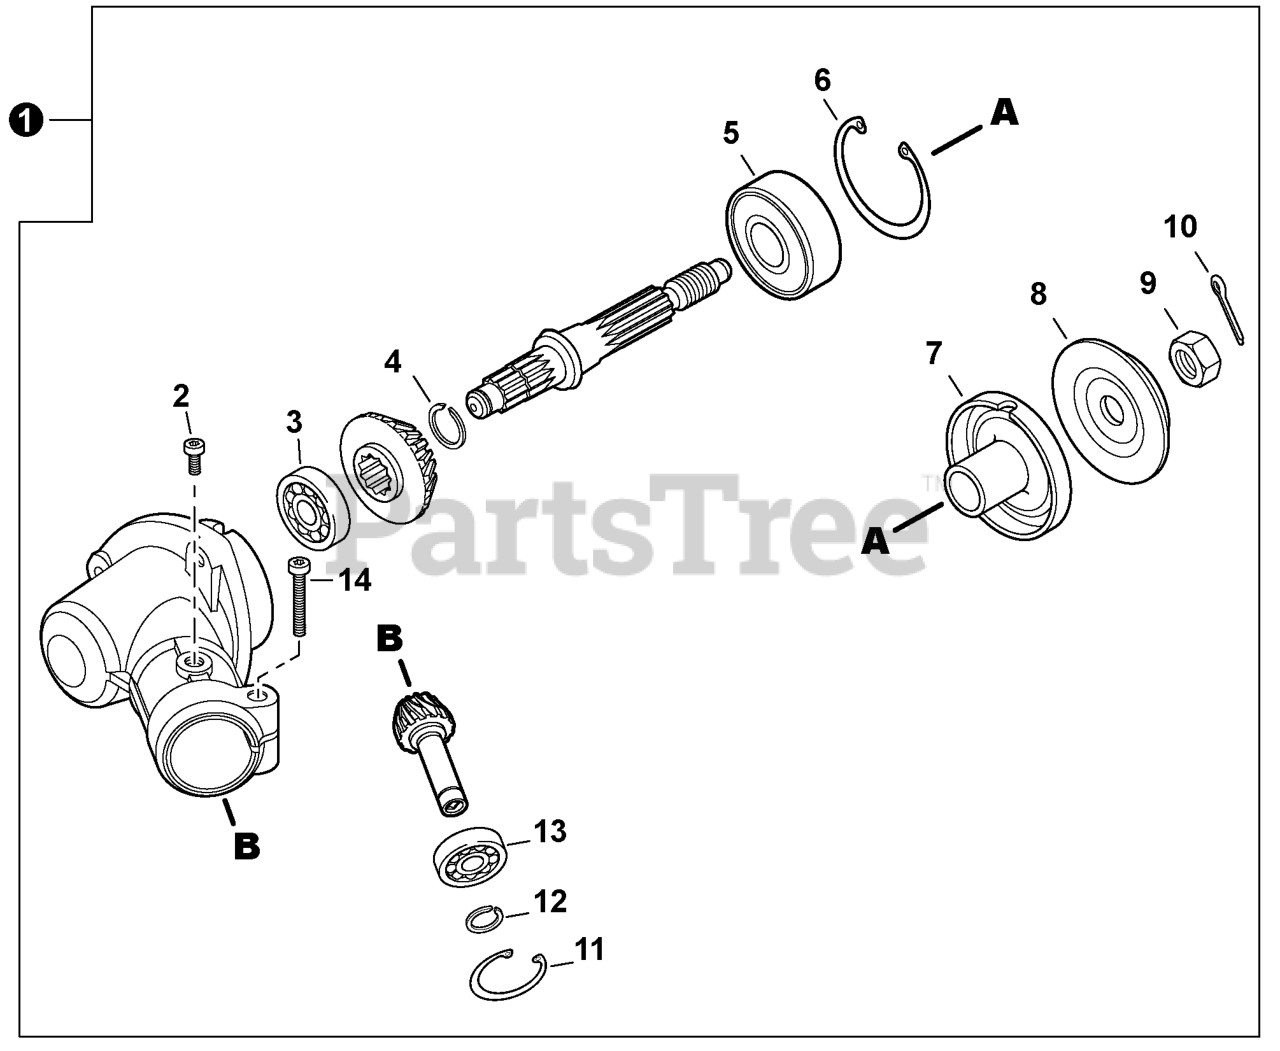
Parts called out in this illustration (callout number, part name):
1	GEAR CASE ASSY
2	BOLT, TORX 5x12
3	BEARING, BALL 609A
4	RING, SNAP 12
5	BEARING, BALL 6201 2RS
6	RING, SNAP 32
7	PLATE, ADAPTOR - UPPER
8	PLATE, ADAPTOR - LOWER
9	NUT 10x1.25 LH
10	PIN, COTTER 2x22
11	RING, SNAP 24
12	RING, SNAP 9
13	BEARING, BALL 609ZA
14	BOLT, TORX 5x25
